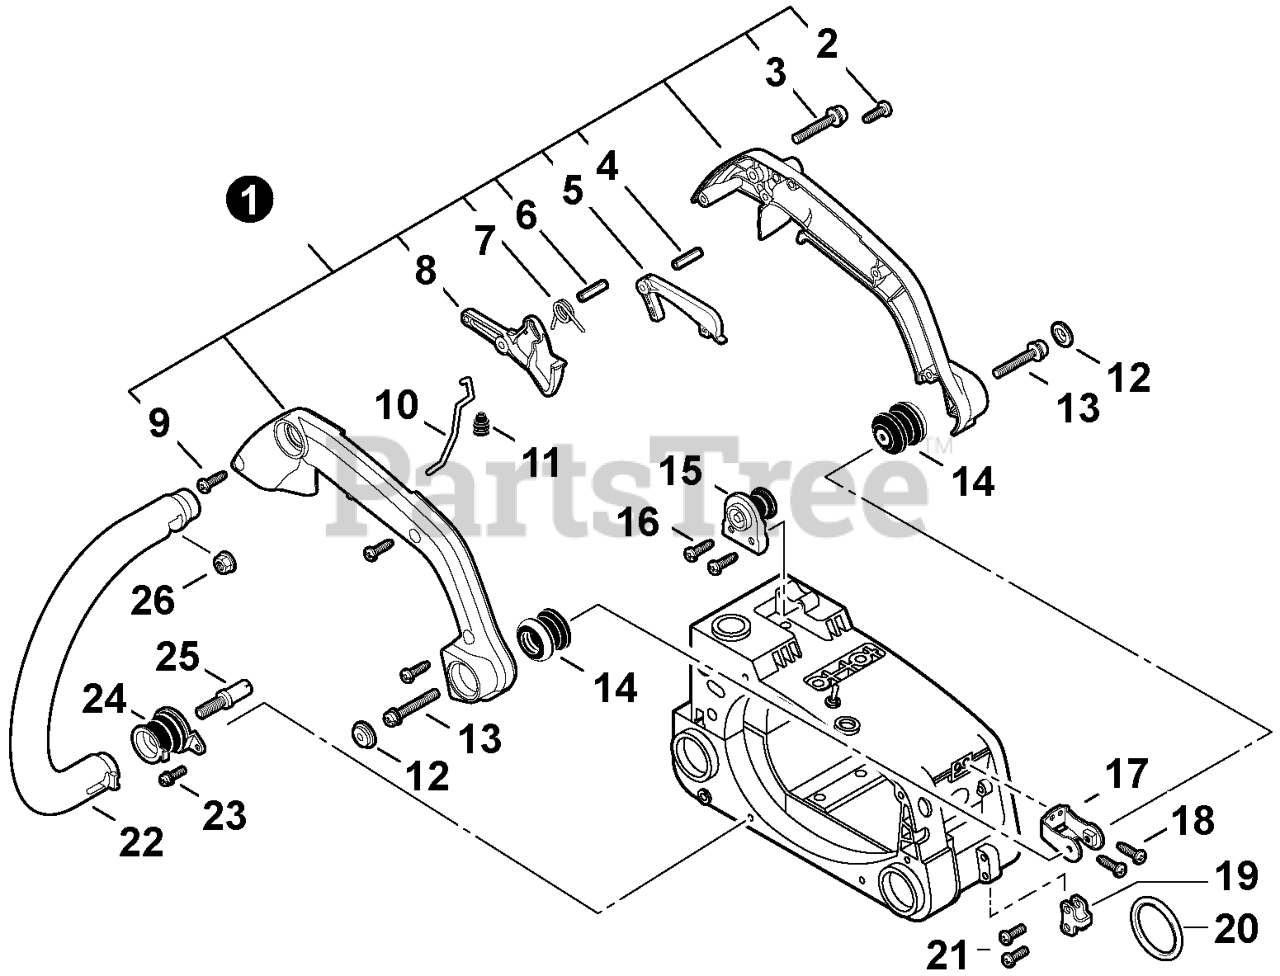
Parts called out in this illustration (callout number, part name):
1	HANDLE SET, REAR
2	SCREW 5x14
3	SCREW 5x35
4	PIN, SPRING 4x20
5	LOCKOUT, THROTTLE
6	PIN, SPRING 4x25 SUS
7	SPRING, TORSION
8	TRIGGER, THROTTLE
9	SCREW 4x16
10	ROD, THROTTLE
11	GROMMET, THROTTLE ROD
12	CAP, CUSHION
13	SCREW 4x10
14	CUSHION 4
15	CUSHION 5
16	SCREW 4x14
17	BRACKET, HANDLE
18	SCREW 4x14
19	BRACKET, HARNESS
20	RING, HARNESS 32
21	SCREW 4x16
22	HANDLE, FRONT
23	SCREW 4x16
24	CUSHION 5
26	NUT, FLANGE M5
